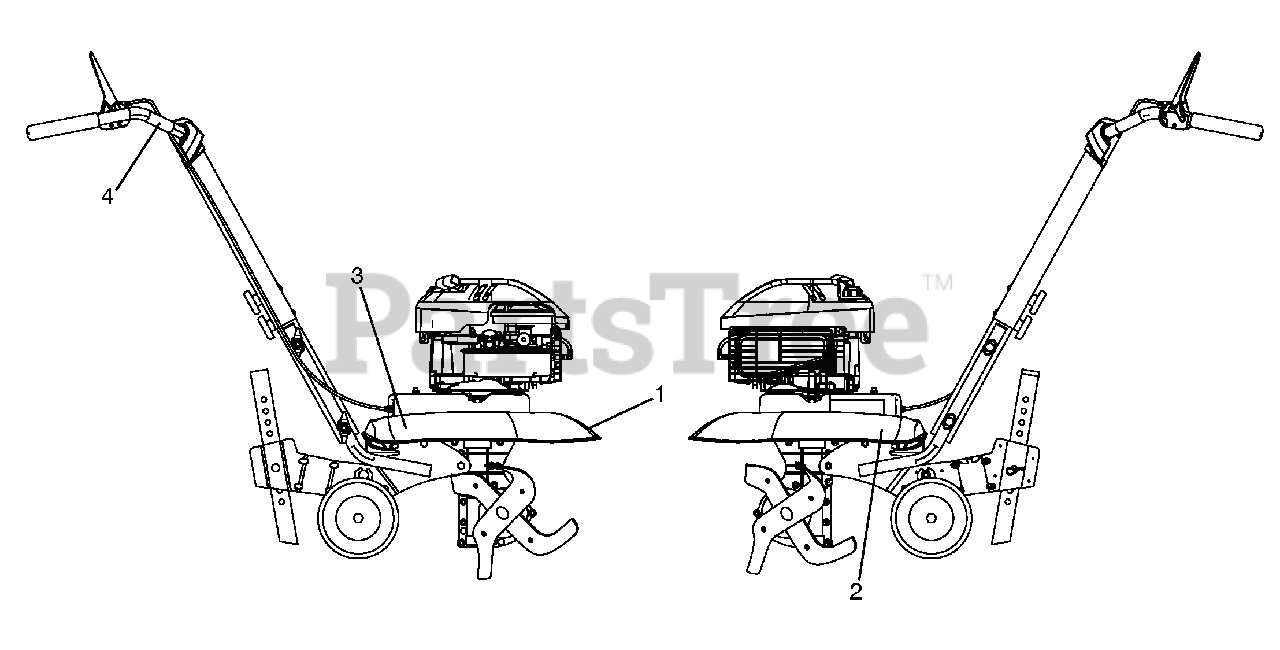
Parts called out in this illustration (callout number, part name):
1	Decal, Tine, Shield, Poulan
2	Decal, Tine, Shield, Warning
3	Decal, Warning, Rotating Tines
4	Decal, Hand Placement
4	Manual, Owner's (Eng/Fren)
